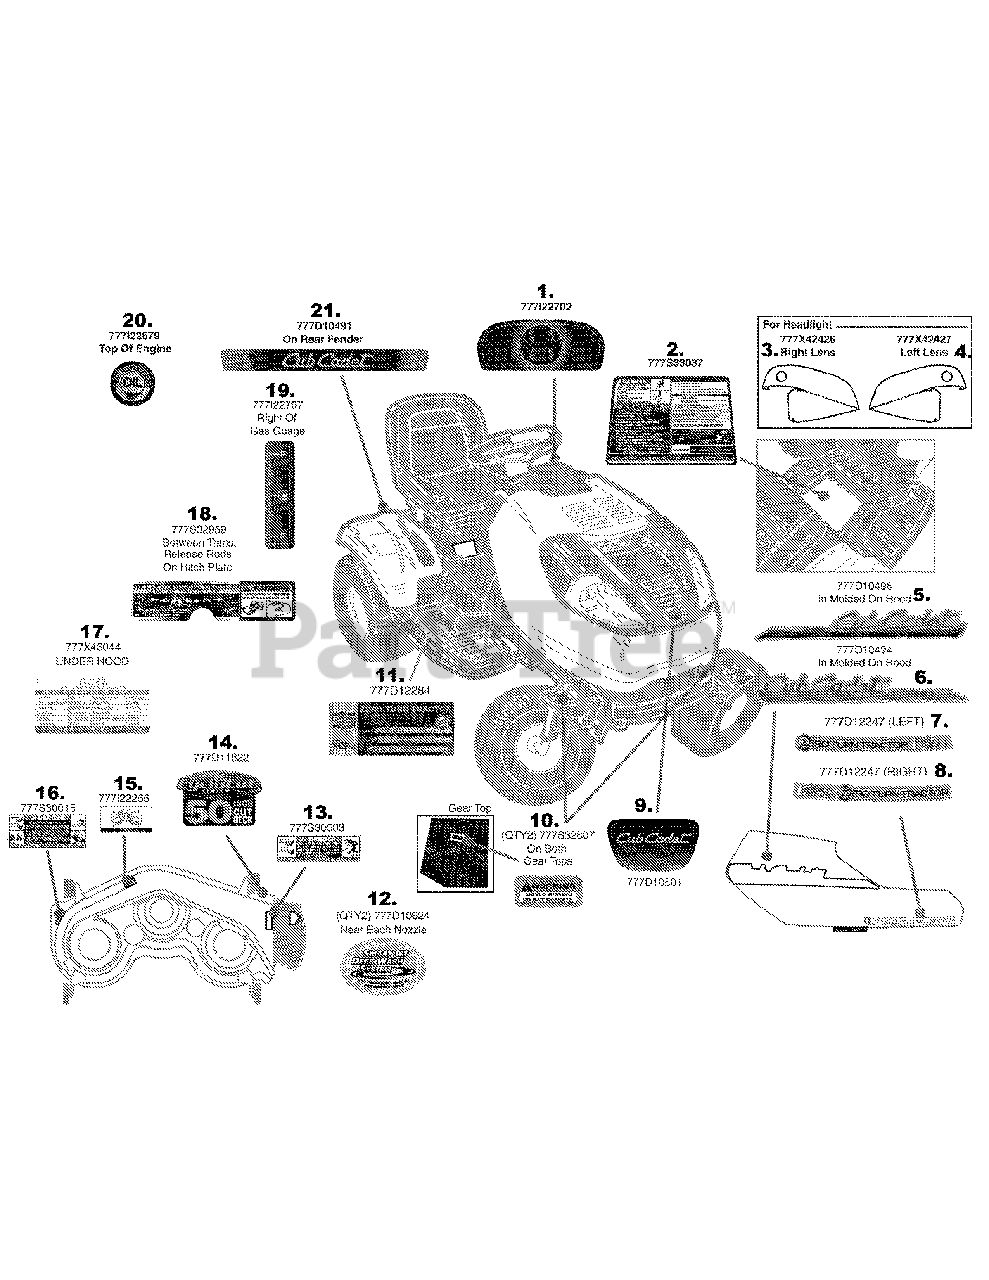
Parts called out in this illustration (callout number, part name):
1	LABEL-RIDER:DASH CUB Z1000
2	LABEL-ZTT TRANSMISN CVR
3	LABEL-RIDER:RT51:LENS DR LFT
4	LABEL-RIDER:RT51:LENS DR RT
5	LABEL-RIDER:HOOD TIME SAVERZ LT
6	LABEL-RIDER:HOOD TIME SAVERZ RT
7	LABEL-ZTT I1050 LH SIDE
8	LABEL-ZTT I1050 RH SIDE
9	LABEL-RIDER:FUEL LEVEL IND CUB
10	LABEL-SAFETY:I1000 SHIELD
11	LABEL-ZTT INFO
12	LABEL-RIDER:DECK WASH CUB
13	LABEL-DANGER CHUTE
14	LABEL-CYCLO CUT 50" BLUE
15	LABEL-BELT ROUTE
16	LBL.RIDER DNGR.STRAIGT
17	LABEL-RIDER PARTS LIST ZTT I1050
18	LABEL-SAFETY I1000 TRANS RELEASE
19	LABEL-RIDER:FUEL LEVEL IND CUB
20	LABEL-RIDER:FENDER TIME SAVERZ
21	LABEL-CHECK ENG OIL
